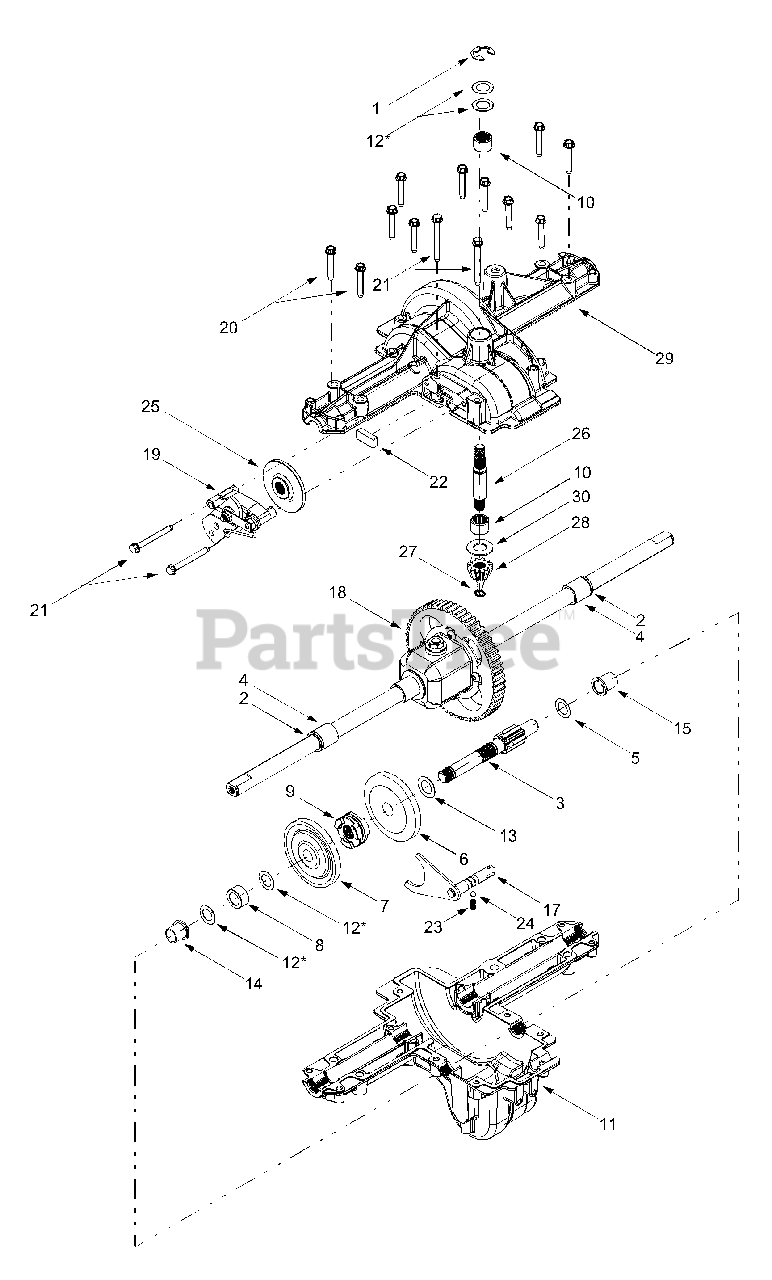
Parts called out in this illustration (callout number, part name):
1	E-ring, .75
2	Seal, .75 x 1.0 x .125
3	Drive Shaft
4	Sleeve Bearing, .75 x .1.0 x 1.0
5	Thrust Washer, 1.0 x .632 x .0
6	42-tooth Bevel Gear .695ID
7	42-tooth Bevel Gear .625ID
8	Spacer, .633 x 1.0 x .513
9	Clutch Collar
10	Needle Bearing, .625 x .813 x 495
11	Lower Housing
12	Flat Washer, 5/8 x 1.0 x .030
12	Flat Washer, 5/8 x 1.0 x .040
12	Flat Washer, 5/8 x 1.0 x .020
13	Flat Washer, .70 x 1.125 x .031
14	Flange Bearing, 5/8 x 3/4 x 3/4
15	Flange Bearing, 5/8 x 3/4 x 15/16
17	Detent Shaft Assembly
18	Differential Assembly
19	Brake Assembly
20	Self-tapping Screw, 1/4-20 x 1.625
21	Self-tapping Screw, 1/4-20 x 2.375
22	Brake Pad
23	Compression Spring
24	Detent Ball
25	Brake Disc
26	Input Shaft
27	Retaining Ring, .437
28	14-tooth Bevel Pinion
29	Upper Housing
30	Thrust Washer, .635 x 1.26 x .06
